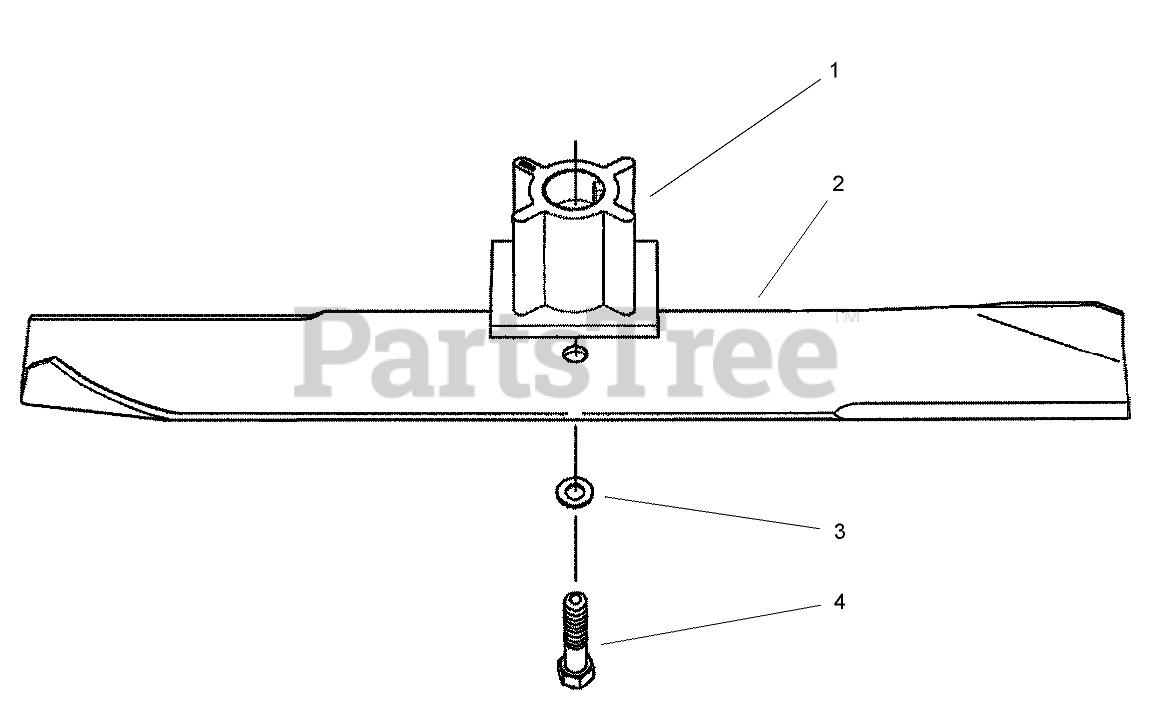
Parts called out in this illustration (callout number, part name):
1	RETAINER-BLADE
2	BLADE-RECYLER
3	WASHER-LOCK
4	BOLT-BLADE
